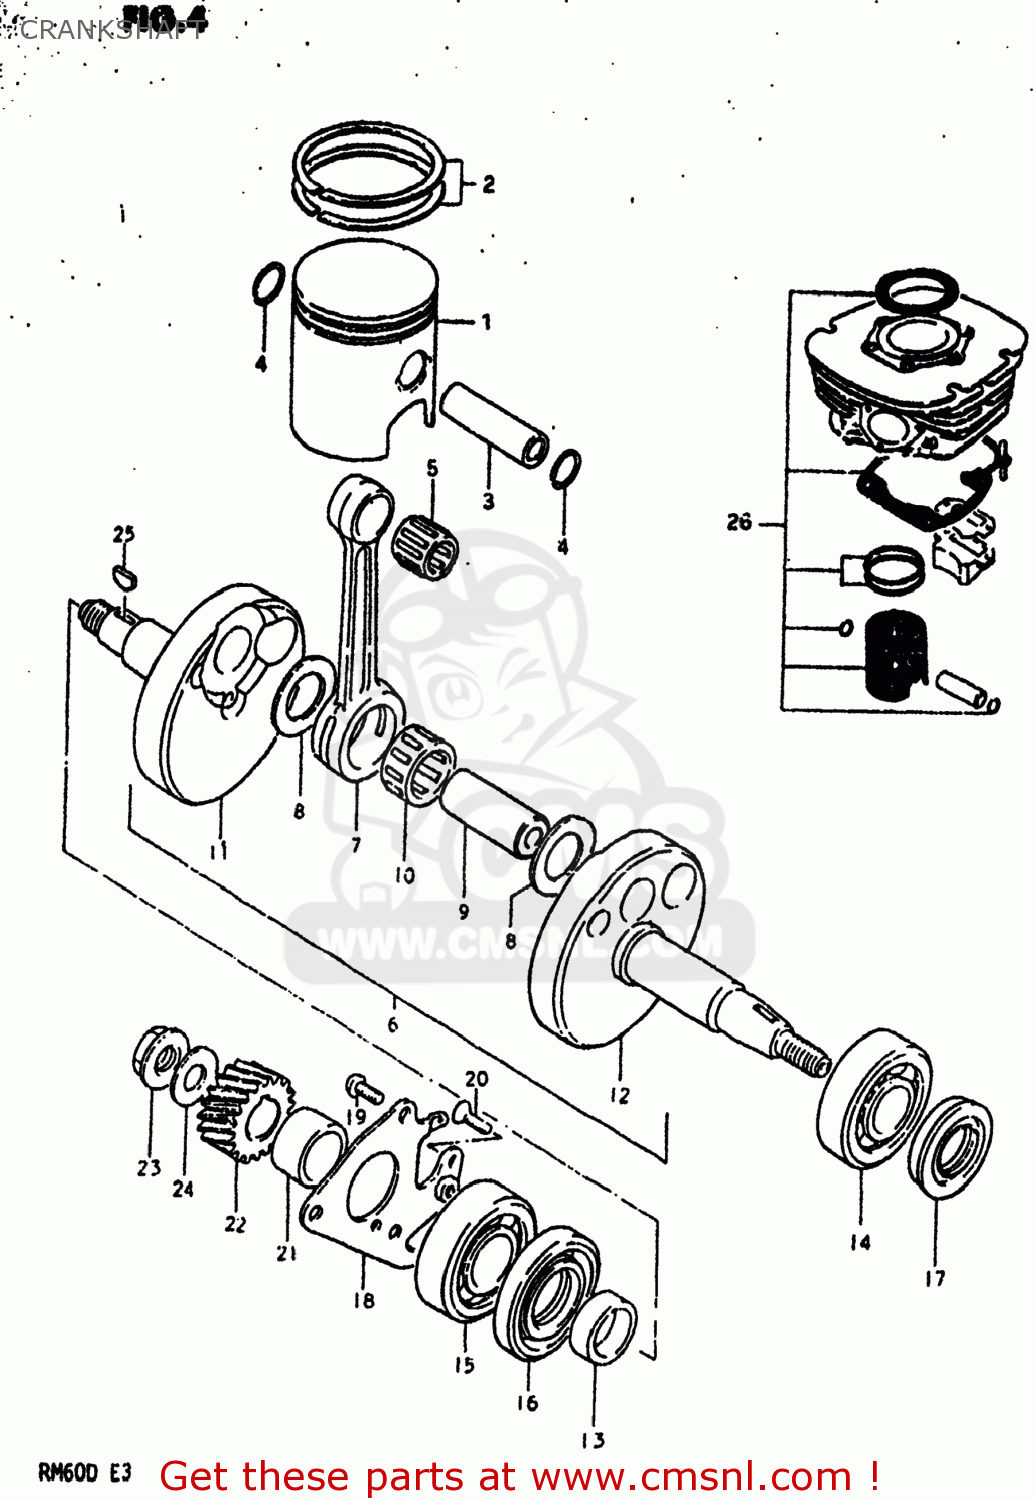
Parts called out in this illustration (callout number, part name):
1	PISTON
2	RING SET,PISTON
3	PIN,PISTON
4	RING,SNAP
5	BEARING
6	CRANKSHAFT ASSEMBLY
7	ROD,CONNECTING
8	WASHER
9	PIN,CRANK
10	BEARING
11	CRANKSHAFT
12	CRANKSHAFT,LEFT
13	SPACER(20X26X9)
14	BEARING
15	BEARING
16	SEAL,OIL(26X47X7.3)
17	SEAL,OIL(19.6X37X8)
18	RETAINER
19	SCREW 6X12
20	SCREW
21	SPACER(20X26X14)
22	GEAR,PRIMARY DRIVE NO.19
23	NUT
24	WASHER
25	KEY
26	PISTON SET
